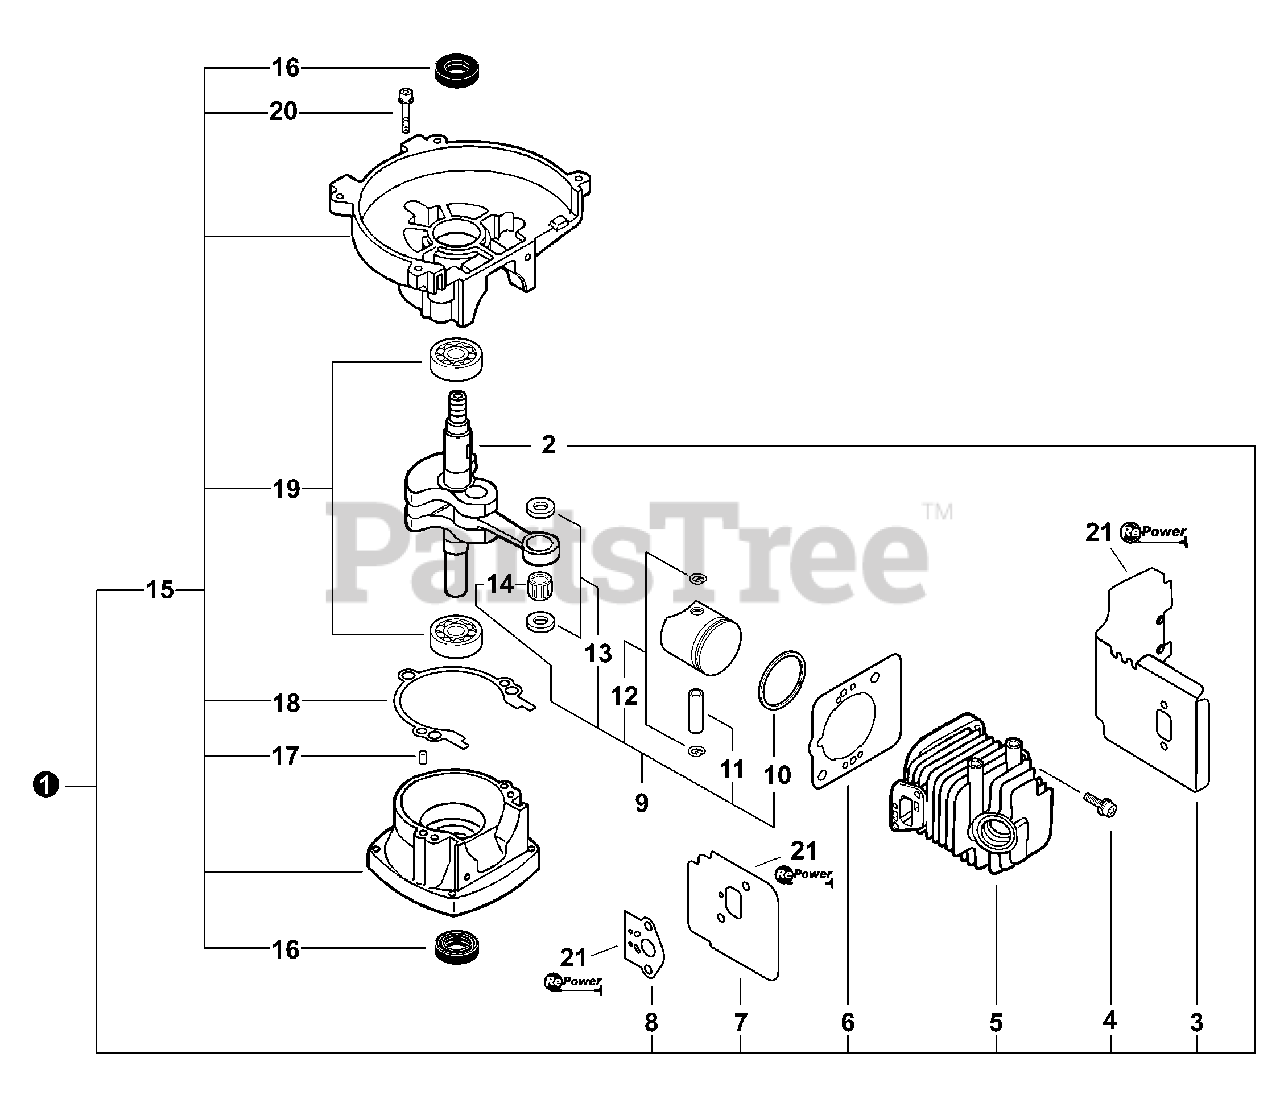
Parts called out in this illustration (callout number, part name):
1	SHORT BLOCK
2	CRANKSHAFT
3	HEAT SHIELD, EXHAUST
4	BOLT 5×22
5	CYLINDER
6	GASKET, CYLINDER
7	HEAT SHIELD, INTAKE
8	GASKET, INTAKE
9	PISTON KIT
10	RING, PISTON
11	PIN, PISTON 8
12	RING, SNAP
13	WASHER, THRUST
14	BEARING, NEEDLE
15	CRANKCASE KIT
16	SEAL, OIL 12
17	PIN, LOCATING 4×8
18	GASKET, CRANKCASE
19	BEARING, BALL - 6201 C3
20	BOLT 5×28
21	GASKET KIT
